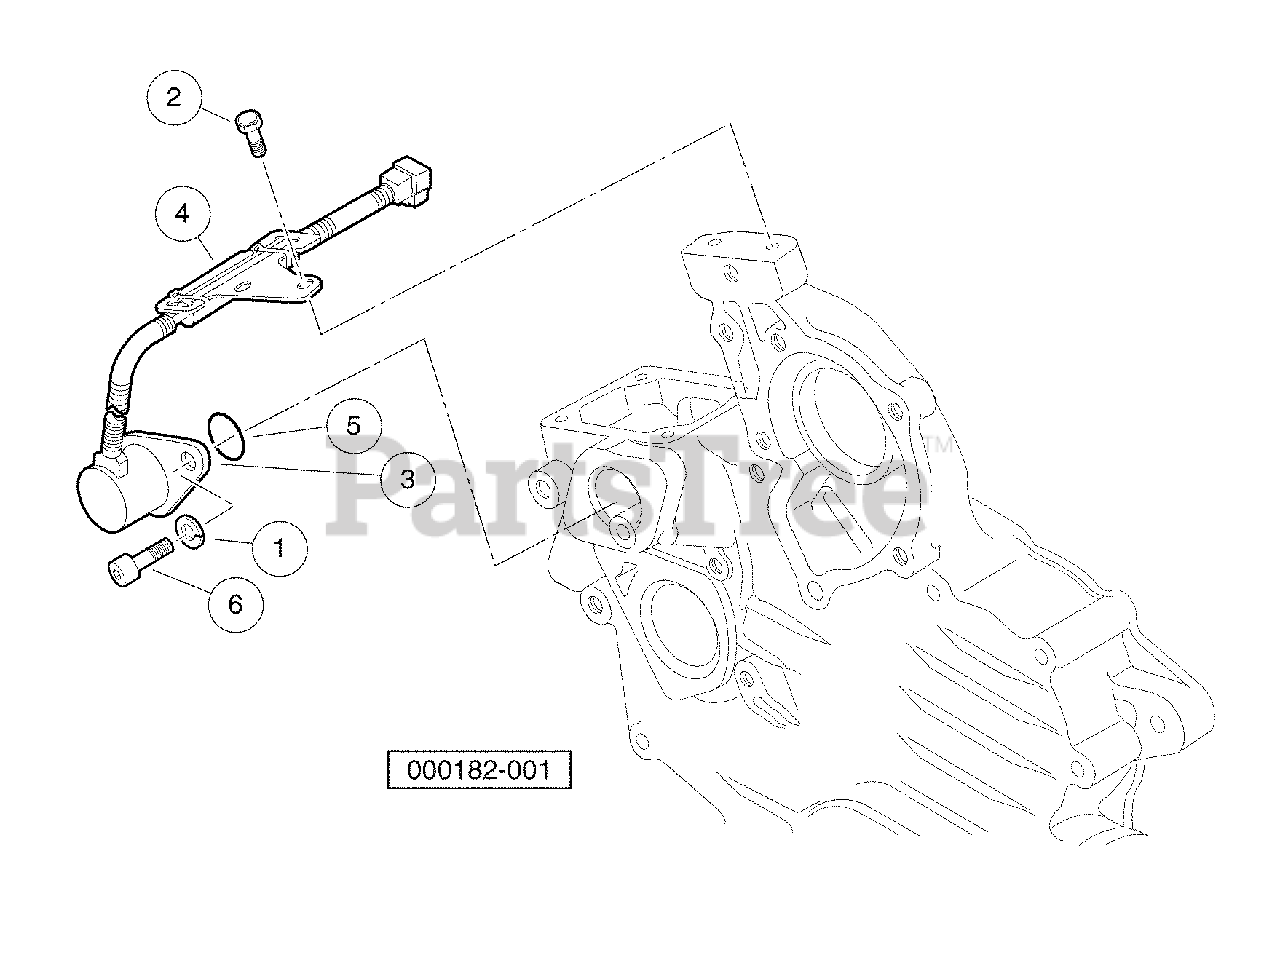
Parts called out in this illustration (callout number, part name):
1	Washer, Spring, M6, D722
2	Bolt, Solenoid, Stop, D722
3	Solenoid, Stop
4	Stay, Stop Solenoid
5	O-Ring, Stop Solenoid
6	Bolt, Stop Solenoid
